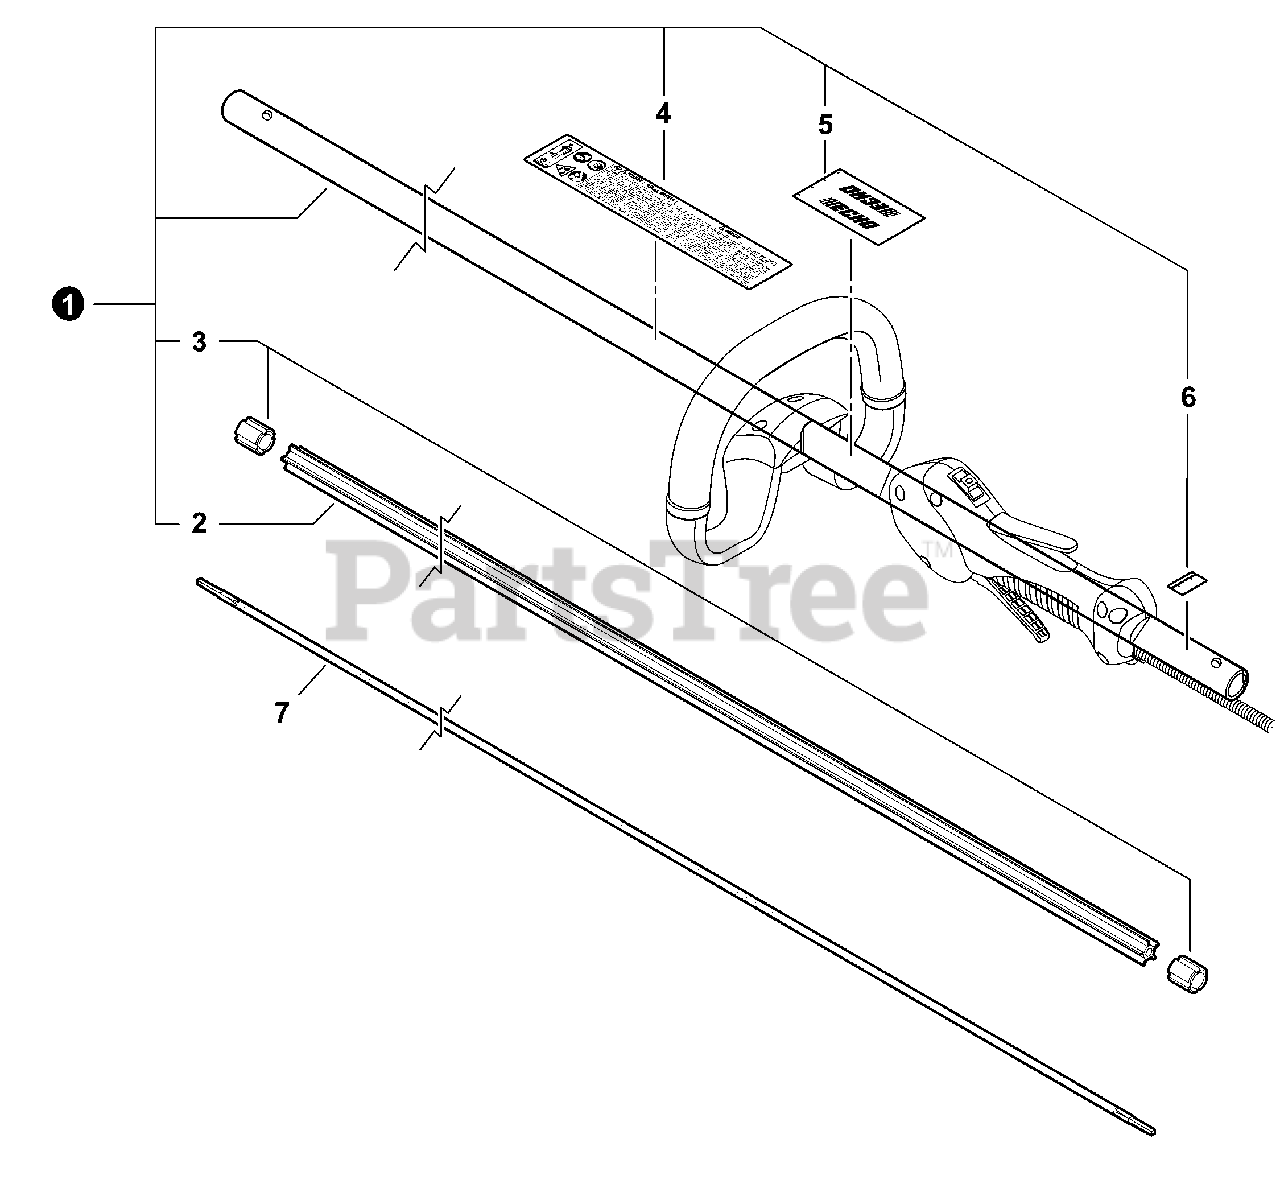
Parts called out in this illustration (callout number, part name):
1	MAIN PIPE ASSY
2	LINER, FLEXIBLE 21.6×1420
4	LABEL, CAUTION
5	LABEL, HANDLE LOCATION
6	LABEL - ALIGNMENT
7	DRIVESHAFT - FLEXIBLE L= 1522
